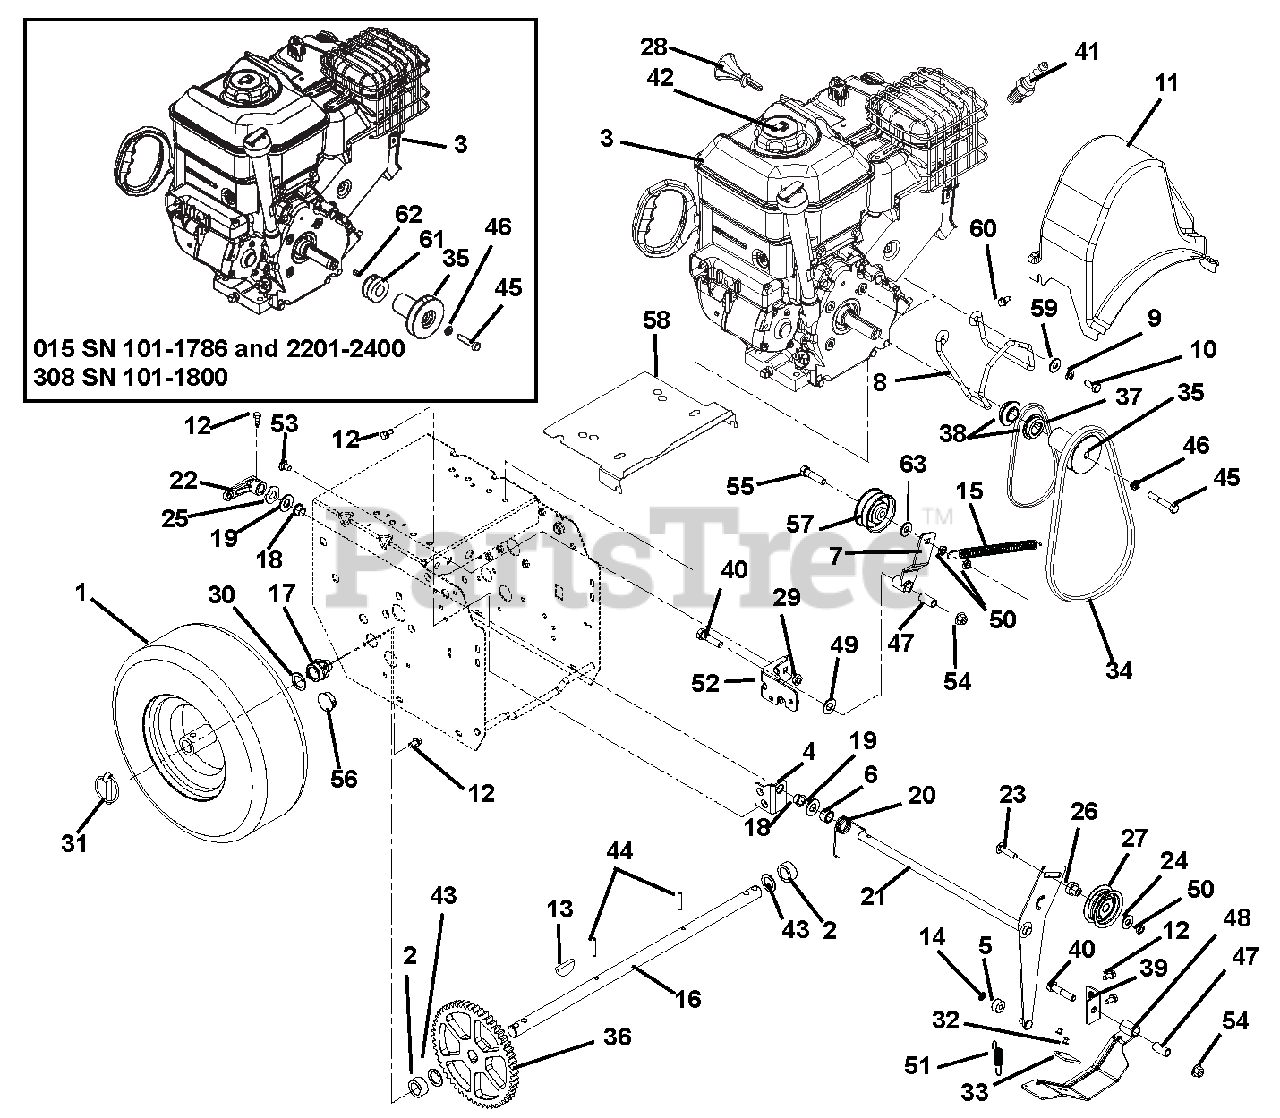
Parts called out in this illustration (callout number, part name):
1	TIRE/WHEEL, RH 4.10-6 PIN K478
1	TIRE/WHEEL, LH 4.10-6 PIN K478
1	TIRE, 4.10-6 K478
1	TIRE/WHEEL, RH 13X5-6 PIN K478
1	TIRE/WHEEL, LH 13X5-6 PIN K478
1	TIRE, 13X5.00-6 K478
2	BSHG-SLV .766 X 1.125 X .500
3	ENGINE, ARIENS 208CC 120V, ALT
3	ENGINE, SUBARU SX17 SNOW 120V
3	ENGINE, BRIGGS SNOW 900,RECOIL
3	ENGINE, BRIGGS 900, 120V 60W
3	ENGINE, BRIGGS SNOW 900, 240V
3	ENGINE, BRIGGS SNOW 1150, 120V
3	ENGINE, BRIGGS SNOW 1150, 240V
3	ENGINE,BRIGGS PF 1150,120V,3/4
3	ENGINE, BRIGGS 1150, 240V, 3/4
4	BRACKET, MOUNT - IDLER ARM
5	BSHG,SLV .265 X .625 X .375
6	BSHG-SLV .510X.751X.475
7	WELDMENT, TRACTION IDLER ARM
8	FINGER, BELT
9	WSHR-LK .312X.097 HVY YWZC
10	BLT-HEX .31-24X.75 YWZC GR5
11	COVER, COMPACT BELT
12	SCR-TAP .25-20X.50 HWH TR YWZ
13	KEY-WDRF .25X.750X.313 SAE91
14	RG-RTNG-EXT .250X.010
15	SG-TENS .062X.56X8.0 WLD 11
16	SHAFT, AXLE
16	AXLE, COMPACT 920,XXX 15" TIRE
17	BSHG .75X1.125X.65
18	BUSHING, POLYLINER-.50 SPLIT
19	@WSHR-FL-STL.531X1.06X.095YWZC
20	SG-TORS .075 X .955
21	WELDMENT, ATTACHMENT IDLER ARM
22	ARM, CLUTCH - ATTACHMENT
23	BLT-RDHDSQSHNK.31-18X1.13 G5YZ
24	@WSHR-FL-STL.38X.875X.083 YWZC
25	WSHR-WAVE .50X.75X.015 .13FRHT
26	SPCR, BRG .315X.50X.688X.281
27	IDLER
28	KEY, PUSH/PULL BRIGGS
28	KEY, PUSH/PULL SUBARU
28	KEY, IGNITION ROTARY B&S
29	@NUT-LK-TOP-FLG .31-18 YWZC
30	WSHR-FL-STL.754X1.125X.062YWZC
30	BSHG-SLV .75X1.12X1.062 NYL BK
31	PIN-LOK .31X1.75
32	RVT-POP .187 YZ
33	PAD, BRAKE
34	V-BELT, HA-RAW EDGE
35	SHEAVE, AUGER - COMPACT
36	SPUR GEAR, 54T .75ID X 6.75PD
37	V-BELT, 3L-WRAPPED
38	TRACTION SHEAVE HALF
39	BRACKET, MOUNT - BRAKE
40	@BLT-HEX .38-16X1.75 GR5 YWZC
41	PLUG, SPARK
41	PLUG, SPARK SUBARU
42	CAP, FUEL - BRIGGS & STRATTON
42	CAP, FUEL SUBARU
43	WSHR-FL-STL.754X1.125X.062YWZC
44	PIN-ROLL .188X1.25
45	@BLT-HEX .31-24X1.75 GR5 YWZC
45	BLT-HEX .38-24X2.0 YWZC
45	BLT-HEX .44-20X1.5 YWZC
46	WSHR-LK .312X.097 HVY YWZC
46	@WSHR-LK .38X.094 REG YWZC
47	BSHG-SLV .385X.500X1.045
48	BRAKE ARM W/PAD
49	@WSHR-FL-STL.406X.812X.065 YWZ
50	@NUT-LK-CTR-JAM .31-18 YWZC
51	SPRING-EXT .437 X .438 X 2.64
52	WELDMENT, FRAME BRACKET
53	@BLT-RHDSSQNK .31-18X.62 G5YZ
54	@NUT-LK-TOP-FLG .38-16 YWZC
55	@BLT-HEX .31-18X1.50 GR5 YWZC
56	PLUG, HOLE - 1.00" FLEXTEMP
57	IDLER,1.875" OD
58	BAFFLE,ENGINE,SMALL BLOCK
59	@WSHR-FL-STL.344X.688X.065YWZC
60	SCR-TAP .25-20X.50 LGHWH TR YZ
61	ENGINE SHEAVE, TRACTION
62	KEY-SQ .188X.188X.375
63	WSHR-FL-STL .344X1.125X.135
